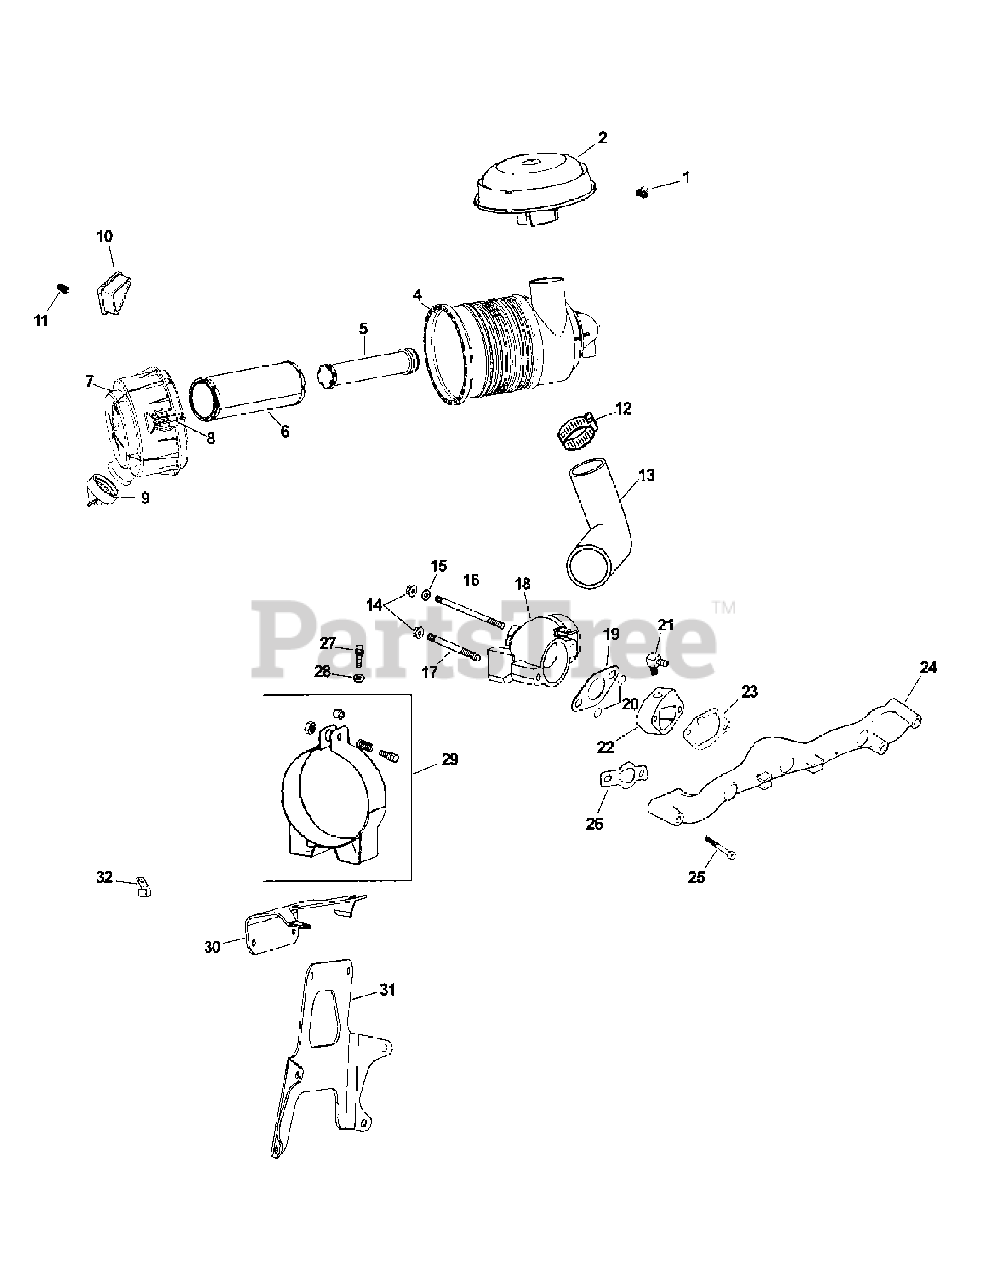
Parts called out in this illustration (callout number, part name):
2	Heavy Duty Air Cleaner Hood
4	Heavy Duty Air Cleaner Housing
5	Air Cleaner Element - Safety
6	Air Cleaner Element - Primary
7	Air Cleaner Cover Assembly
8	Clip
9	Dust Ejector Valve
10	Blower Housing Cover
11	Tapping Screw
13	Air Cleaner Hose
14	Hex Lock Nut (M6 x 1.0)
15	Copper Washer (1/4")
16	Stud (M6 x 1.0 x 180)
17	Stud (M6 x 1.0 x 40)
18	Elbow Adapter
19	Air Cleaner Adapter Gasket
21	Hose Connector
22	Remote Air Cleaner Adapter
23	Air Cleaner Base Gasket
24	Intake Manifold
25	Hex Flange Screw (M6 x 1.0 x 55)
26	Intake Manifold Gasket
27	Hex Flange Screw (M6 x 1.0 x 16)
28	Plain Washer (1/4")
29	Air Cleaner Bracket
30	Air Cleaner Mounting Bracket
31	Main Support Bracket
